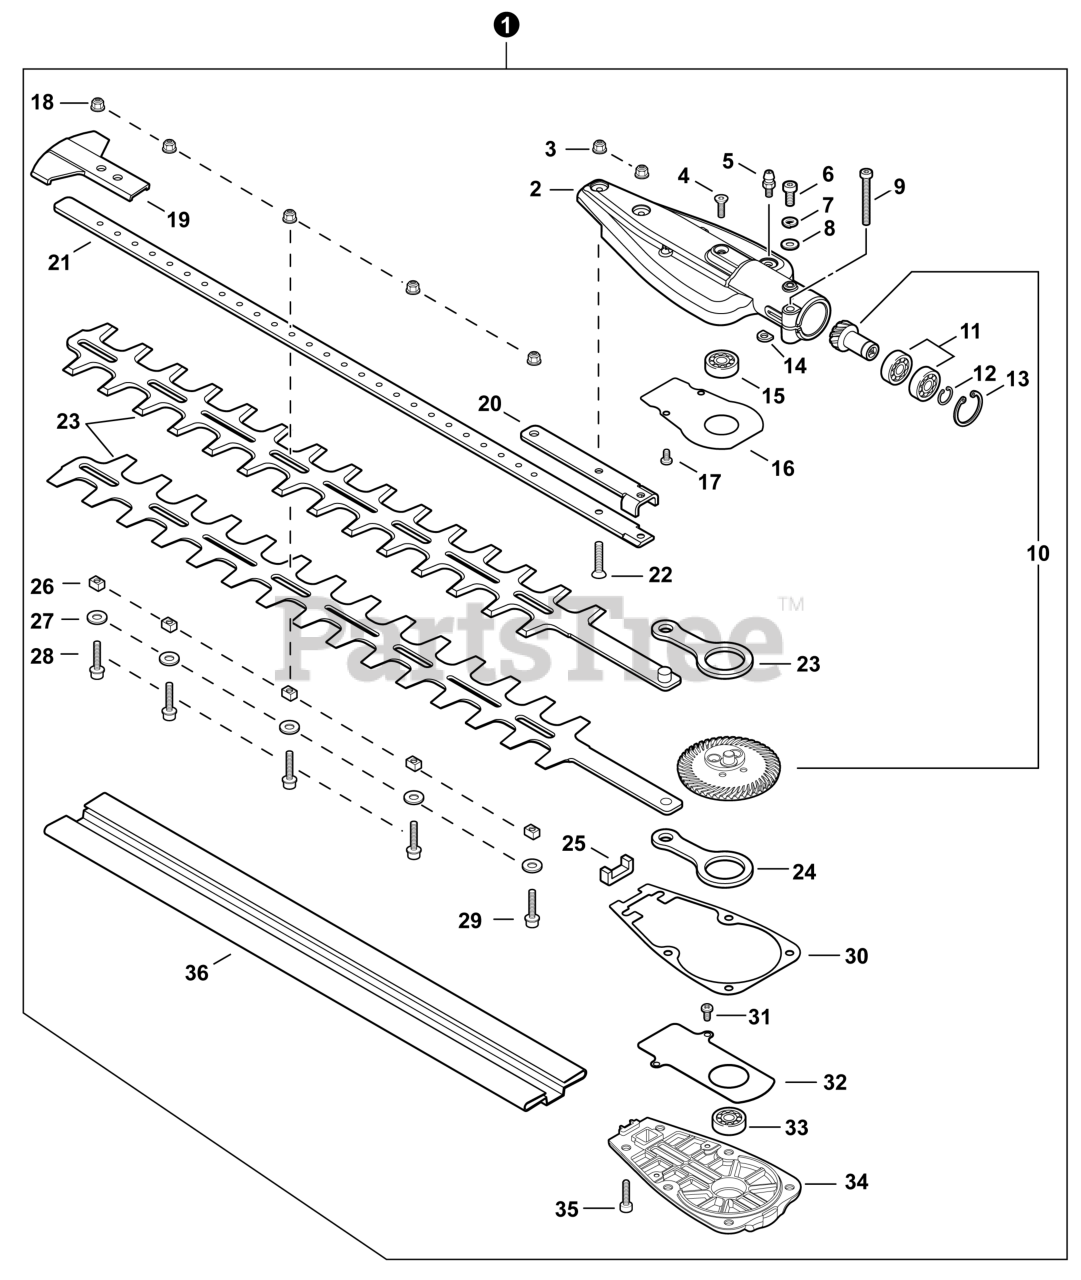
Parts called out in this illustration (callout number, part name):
1	CUTTING HEAD KIT
2	HOUSING, GEAR CASE
3	NUT, FLANGE M5
4	SCREW 5x5/8" HD-SOCKET
5	FITTING, GREASE
6	BOLT, TORX 5x12
7	WASHER, SPRING 5
8	WASHER, FLAT 5.5x10x0.8
9	BOLT, TORX 5x25
10	GEAR SET, BEVEL
11	BEARING, BALL
12	RING, SNAP 12
13	RING, RETAINING 24
14	D-WASHER
15	BEARING, BALL 608ZZ
16	PLATE, WEAR
17	SCREW 4x5
18	NUT, FLANGE M5
19	GUARD, TIP
20	SUPPORT, BLADE
21	SUPPORT, BLADE
22	SCREW 5x18
24	ROD, CONNECTING
26	GUIDE, BLADE 5
27	WASHER 5
28	BOLT 5x20
29	BOLT, FLANGE 5x22
30	GASKET, GEAR CASE
31	SCREW 4x5
32	PLATE, WEAR
33	BEARING, BALL 628ZZ
34	COVER, GEAR CASE
35	BOLT 5x12
36	SCABBARD
